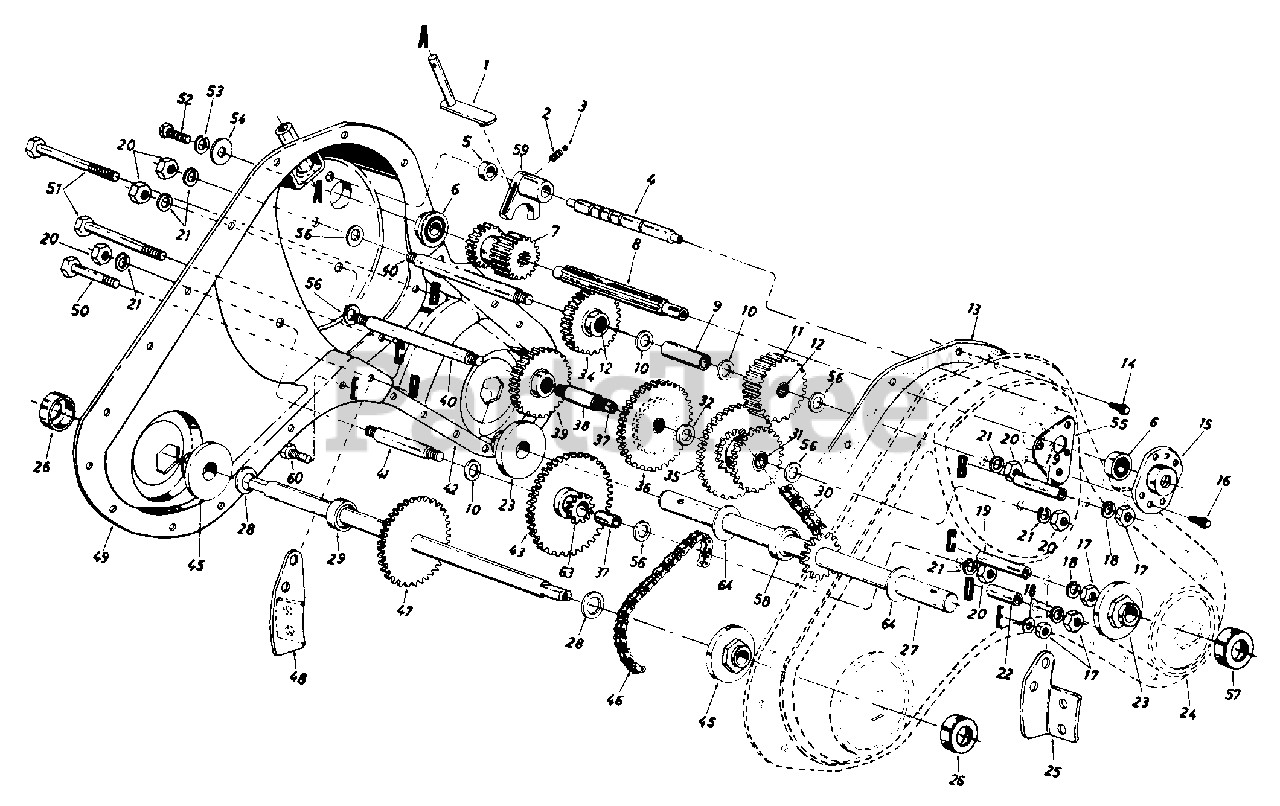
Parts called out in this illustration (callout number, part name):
1	Shifting Bracket Ass'y.
2	Compression Spring .50" Lg.
3	Ball Detent .250" Dia.
4	Detent Shaft 1/2" Dia.
5	Spacer 505" I.D. x .88" O.D.
6	Ball Brg. .62" I.D. x 1.38"
7	Spur Gear 16T
8	Input Spline Shaft 7/8"
9	Spacer .657" I.D. x 2.85" Lg.
10	Fl-Wash. .640" I.D. x 1.24"
11	Spur Gear 30T 7/8" I.D.
12	Needle Bearing 5/8" I.D.
13	Gasket Trans. Hsg.
14	Hex Wash. S-Tap Scr. 1/4-20 x .50" Lg.
15	1-3/8" Dia. Bearing Housing
16	Hex TT-Tap Scr. 1/4-20 x .75"
17	Hex Nut 5/16-18 Thd.
18	L-Wash. 5/16" I.D.
19	Spacer 1.56" Lg.
20	Hex Nut 7/16-20 Thd.
21	Bell-Wash. .45" I.D. x 1.0"
22	Spacer 1.015" Lg.
23	Tine Shaft Brg. 1.002 x 2.50
24	Trans. Housing Ass'y. L.H.
27	Tine Shaft Ass'y. 1" O.D.
28	Fl-Wash. .75" I.D. x 1.5" O.D.
29	Spacer .75" I.D. x .50" Lg.
30	Chain #50 5/8 Pitch x 52 Links Endless
31	Needle Bearing 5/8" I.D.
32	Fl-Wash. 5/8" I.D.
34	Spur Gear 30T 12/16" I.D.
35	30/44T Gear Ass'y. Comp.
36	Spur Gear 44T
37	Sleeve Bearing
38	Gear Hub 3/4" I.D. x 3" Lg.
39	Spur Gear 30T 1.0" I.D. x 1/2" W
40	Jack Shaft 5/8" Dia. x 5"
41	Jack Shaft 5/8" Dia. x 2.38"
45	Wheel Brg. .752" x 2.5"
46	#420 Chain 1/2 Pitch x 50 Links Endless
47	Wheel Shaft Ass'y. 15.6"
51	Hex Bolt 5/16-18 x 2.5"
52	Hex Bolt 1/4-20 x .62" Lg.
53	L-Wash. 3/8" I.D.
54	Fl-Wash. 1/4" I.D. x .93" O.D.
55	Gear Positioner Bracket
56	Fl-Wash. 7/16" I.D. x 1-3/8"
57	Dust Cover Ass'y. 1" Shaft
58	Spacer 1" I.D. x 2" O.D.
59	Shifting Fork
60	Hex Bolt 5/16-18 x .75" Lg.
63	10T Sprocket Ass'y.
64	Thrust Wash. 1.03" I.D. x 1.62" O.D.
